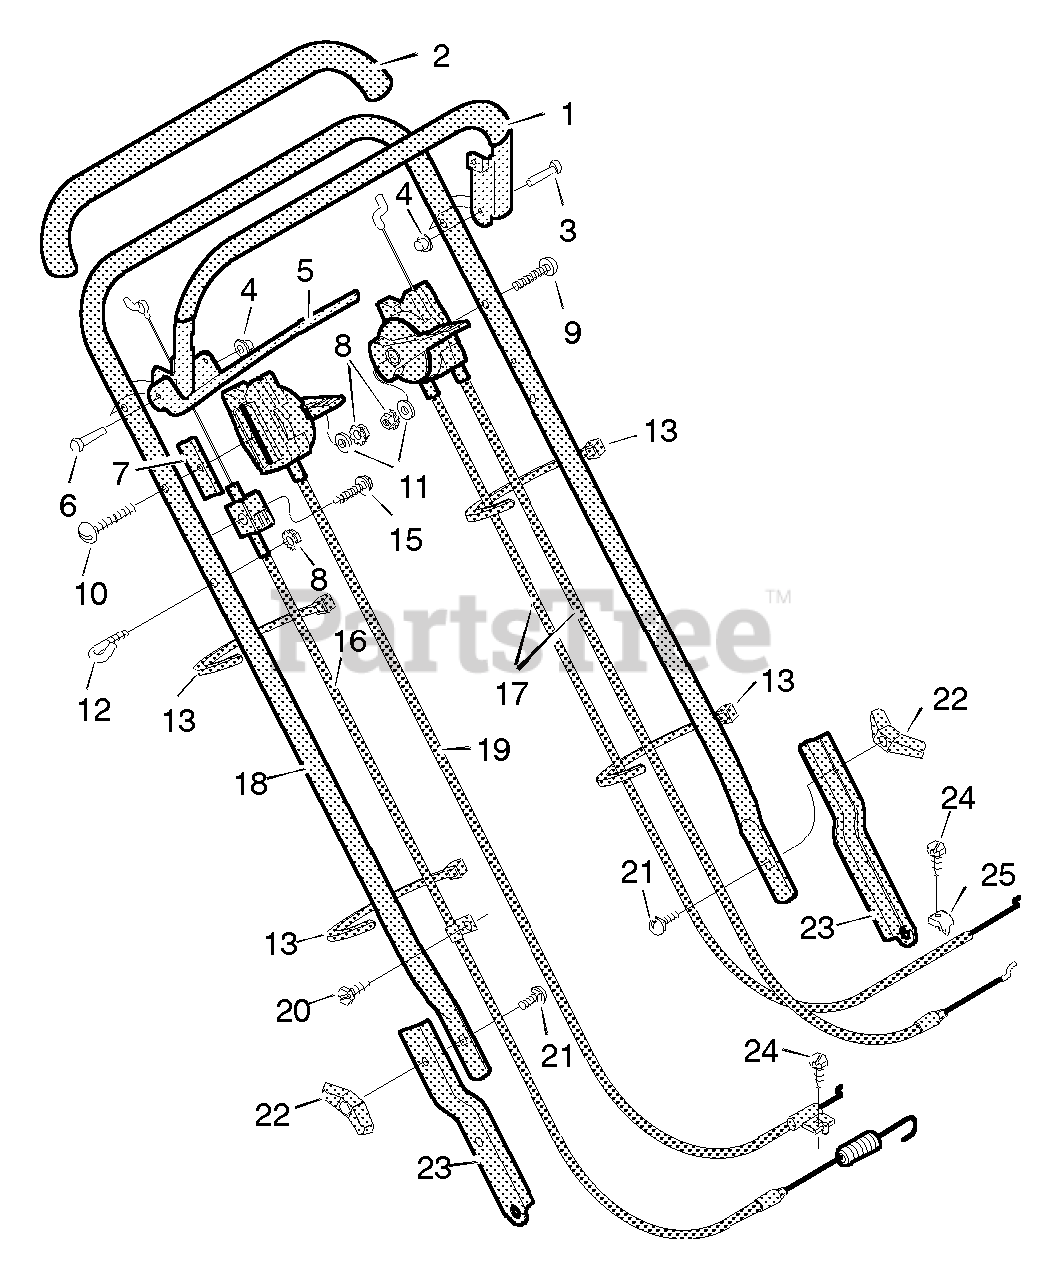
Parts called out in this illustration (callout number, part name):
1	Stop Lever
2	Grip, Foam
4	Push On Cap
5	Lever, Drive
7	Spacer
8	Locknut
12	GUIDE, ROPE
13	Fastener, Cable
16	Cable, Drive
17	Throttle and Stop Cable
19	Control, Speed
21	Bolt, Carriage
23	Bracket, Handle
